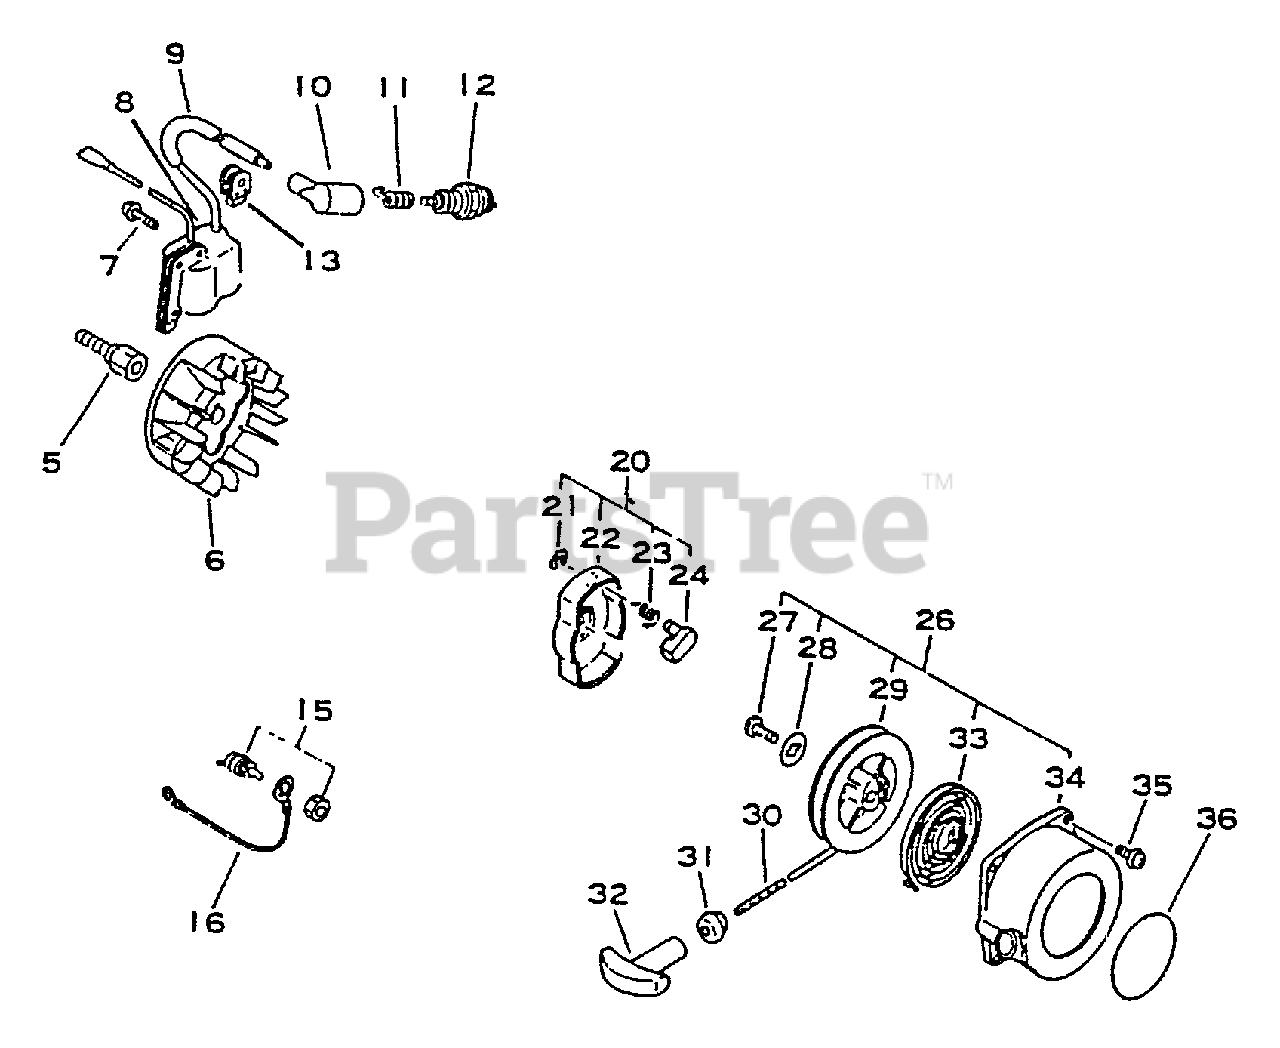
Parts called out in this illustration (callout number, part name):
5	HUB, FAN
6	FLYWHEEL
7	SCREW - 4X22
8	COIL, IGNITION
10	CAP, SPARK PLUG
11	TERMINAL, SPARK PLUG CAP
12	SPARK PLUG -- BPM-7A
12	SPARK PLUG -- BPMR-7A
15	IGNITION SWITCH ASSY
16	LEAD - GROUND
20	STARTER PAWL ASSY
21	RING, RETAINING - 4
22	CATCHER, PAWL
23	SPRING, RETURN
24	PAWL, STARTER
26	STARTER ASSY
28	WASHER
29	REEL, ROPE
30	ROPE, STARTER - 3X890
31	GUIDE, ROPE
32	GRIP, STARTER
33	SPRING, REWIND
34	CASE, STARTER
35	SCREW - 4X18
36	LABEL - ECHO
